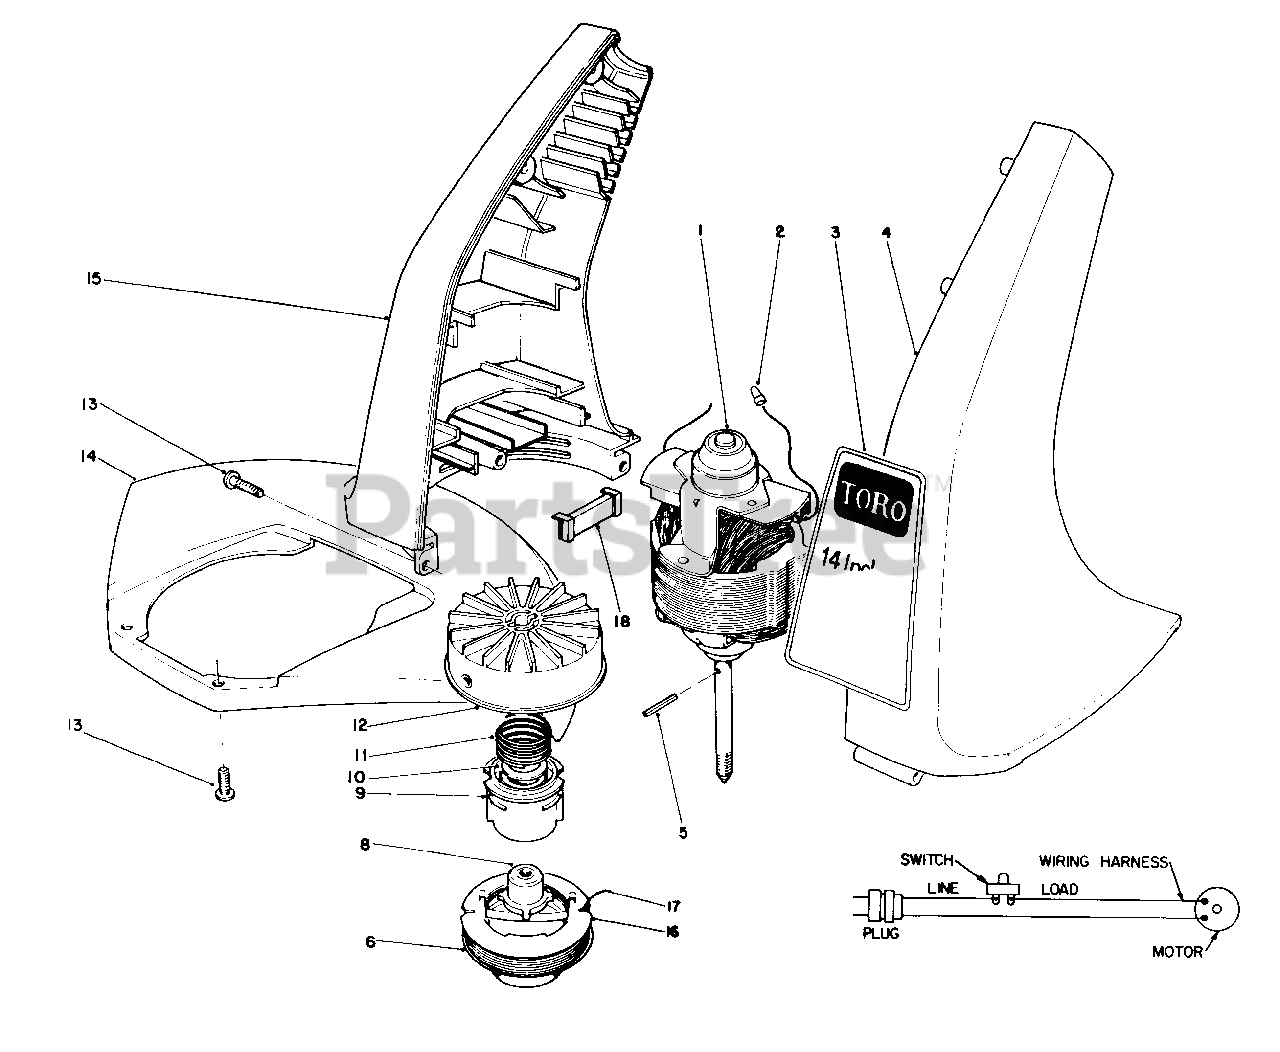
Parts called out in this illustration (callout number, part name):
2	Connector-Wire
3	Decal-14 Inch
4	Housing-L.H.
6	50 Ft. 065 Dia. Cutting Line Prewound on Spool
12	Drum w/Eyelet
13	Screw
15	Housing-R.H.
16	Empty Spool
17	50 Ft. Coil-.065 Dia. Cutting Line in Coil
18	Insert-Housing
